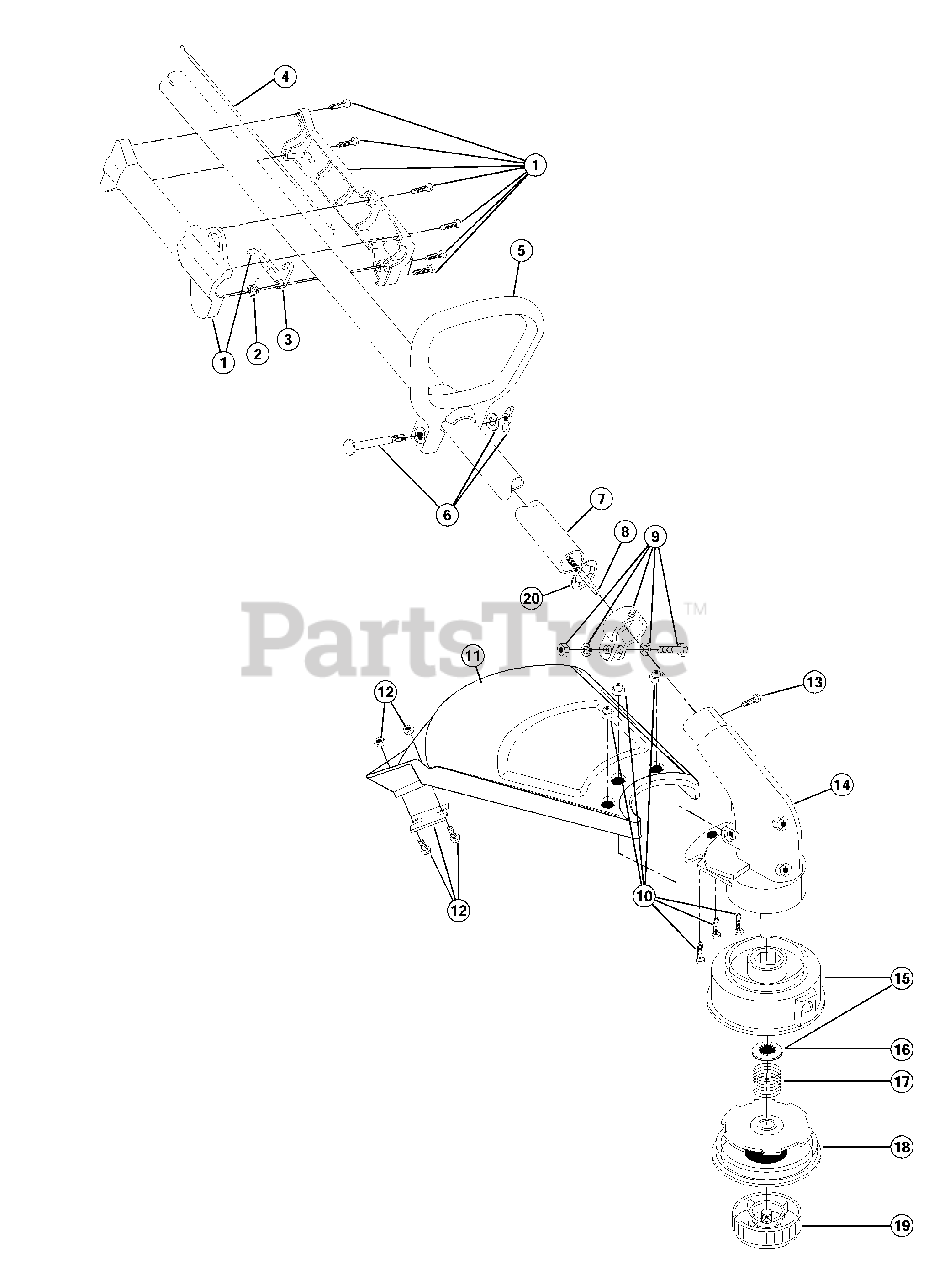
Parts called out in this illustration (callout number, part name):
1	Throttle Housing and Trigger Assembly
2	Throttle Trigger Spring
3	Throttle Trigger
4	Throttle Cable
5	D-Handle
6	D-Handle Hardware Assembly
7	Drive Shaft Housing Assembly
8	Flexible Drive Shaft
9	Lower Clamp Assembly
10	Guard Mounting Screw Assembly
11	Guard and Blade Assembly
12	Blade Assembly
13	Anti-Rotation Screw
14	Gearbox Assembly
15	Outer Spool and Eyelet Assembly
16	Retainer (10 pack)
17	Spring
18	Inner Reel
19	Bump Head Knob Assembly
20	Retainer
